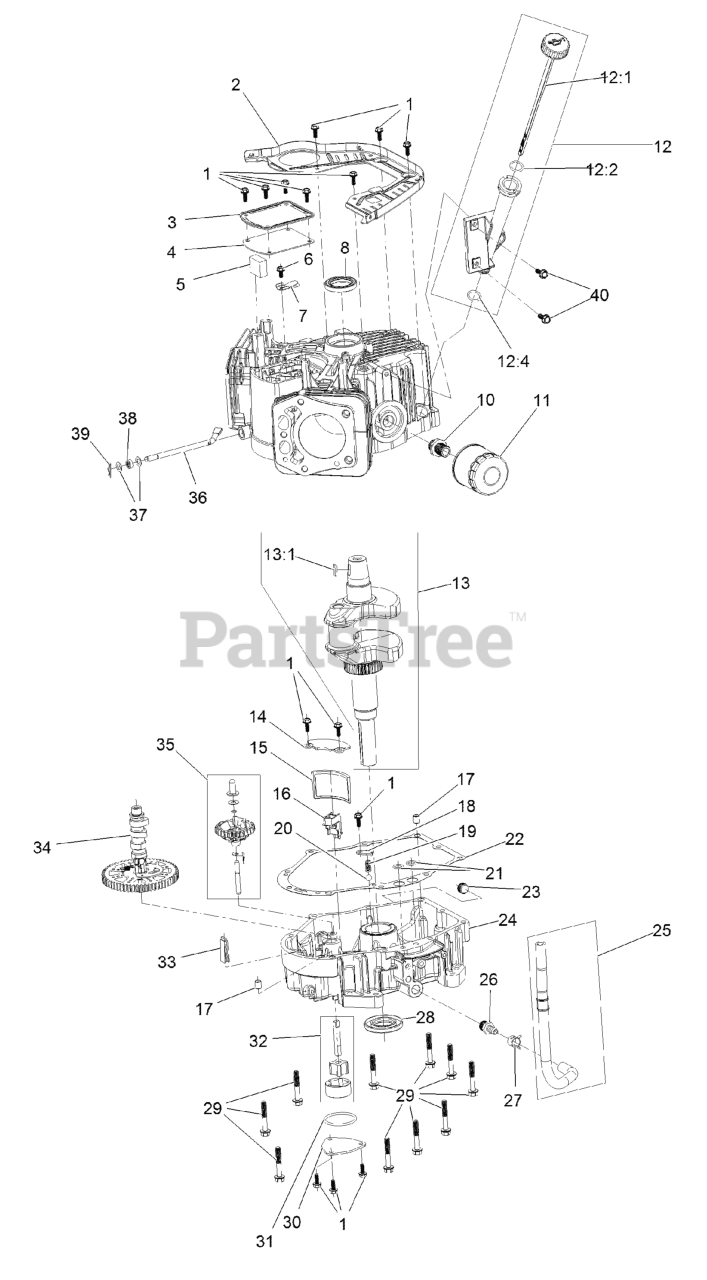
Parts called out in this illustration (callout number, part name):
1	SCREW-HHF
3	COVER-BREATHER
4	GASKET-BREATHER
5	FILTER-BREATHER
6	SCREW-HHF
7	VALVE-BREATHER
8	SEAL-OIL
10	ADAPTOR-FILTER, OIL
11	FILTER-OIL
12	OIL TUBE ASM
12:1	DIPSTICK
13	CRANKSHAFT
13:1	KEY-WOODRUFF
14	COVER-SCREEN, OIL
15	SCREEN-OIL
16	RETAINER-SCREEN
17	PIN-DOWEL
18	PLATE-RETAINER
20	VALVE-BALL
22	GASKET-COVER, CRANKCASE
23	PLUG-DRAIN
24	COVER-CRANKCASE
25	OIL DRAIN HOSE ASM
26	FITTING-HOSE
27	CLAMP-HOSE
29	SCREW-HHF
30	COVER-OIL PUMP
32	OIL PUMP ASM
33	DEFLECTOR-OIL, RUBBER
34	CAMSHAFT
35	GOVERNOR ASM
36	SHAFT-GOVERNOR
37	WASHER-PLAIN
38	SEAL-OIL
39	PIN-HAIR
40	SCREW-HHF
